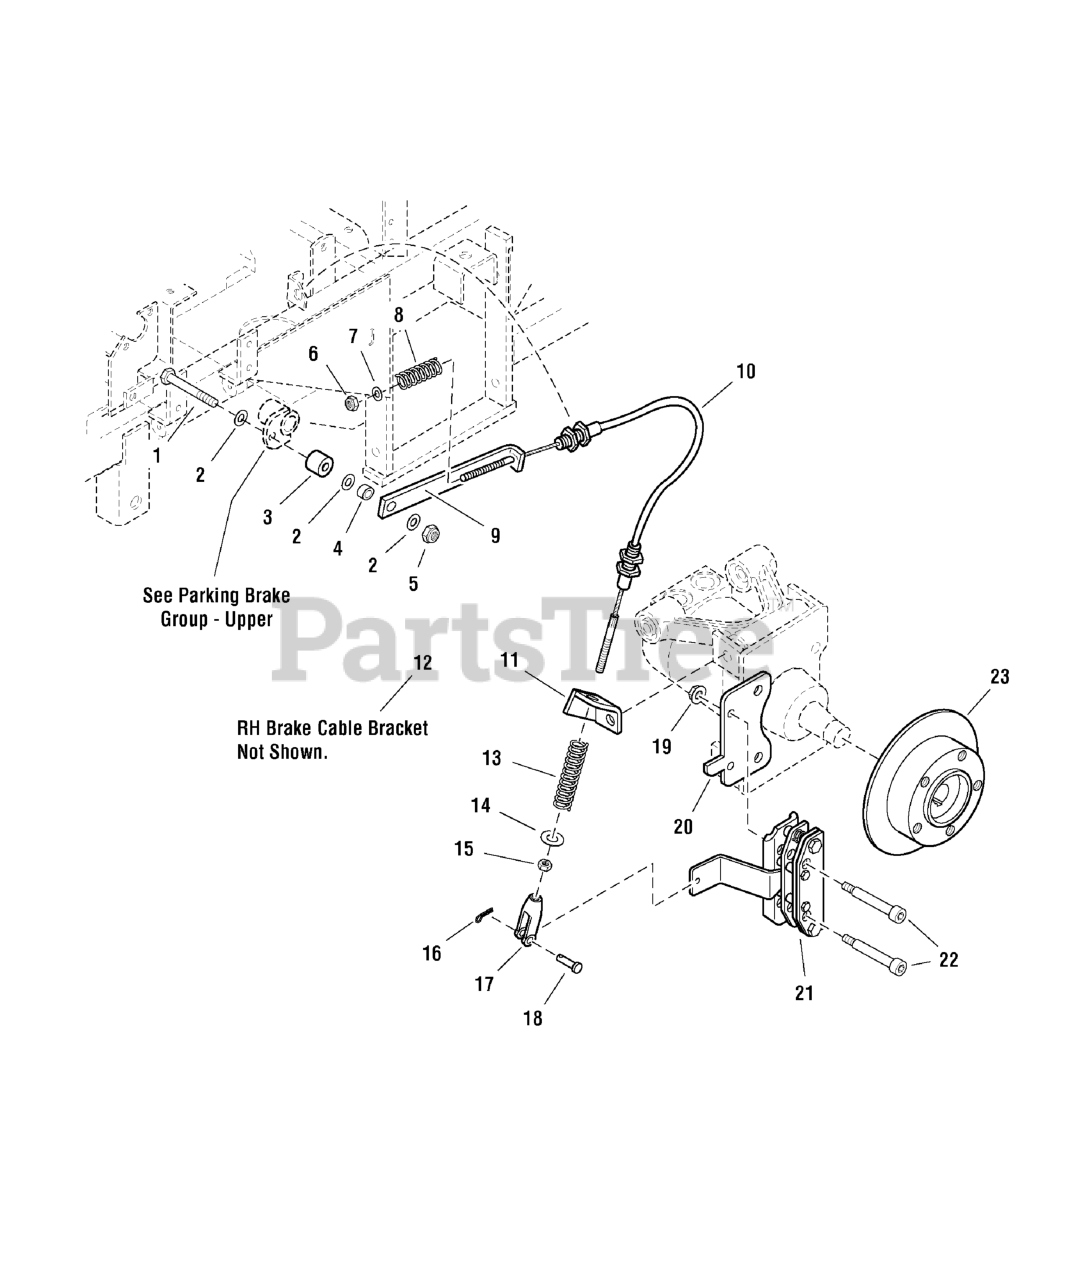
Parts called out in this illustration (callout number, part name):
1	BOLT, 3/8-16 X 2-1/4" GD5 CZ
2	WASHER, 3/8 SAE
3	SPACER, .39 x 1.00 x .88
4	SPACER, .38 x .50 x .27
5	NUT, 3/8-16 HEX NYLON LOCK
6	NUT, 5/16-24 HEX NYLON LOCK
7	WASHER, 5/16" SAE
8	SPRING, Compression
9	LINK, Brake Lock
10	CABLE, Brake
11	BRACKET, Brake Cable -LH
13	SPRING, Compression
14	WASHER, 5/16" Fender
15	NUT, 5/16-24 Hex
16	PIN, COTTER, 1/8 X 1-1/4
17	CLEVIS, 5/16-24, STEEL, CLEAR ZINC
18	CLEVIS PIN, 5/16 x 1
19	NUT, 3/8-16 Hex Serrated Flange
20	BRAKE CALIPER MOUNT
21	BRAKE CALIPER
22	SHOULDER BOLT, 1/2" x 2-3/4"
23	WHEEL HUB, COMPACT CALIPER (86720)
